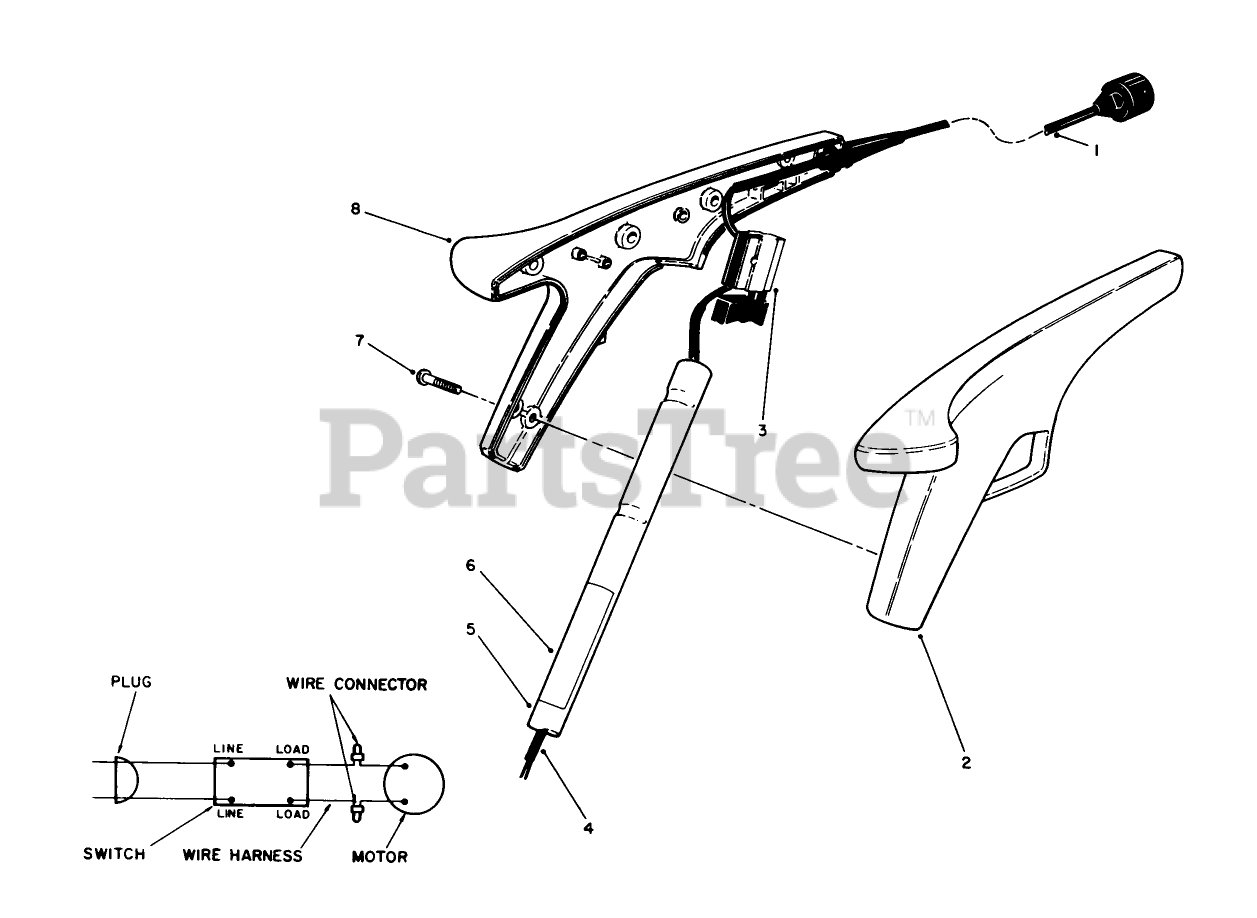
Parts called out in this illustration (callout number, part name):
1	Cord-Power
2	HAND GRIP, 8" - L.H.
3	SWITCH SINGLE SPEED
4	WIRE HARNESS
5	TUBE EXTENSION
7	#8 X .625" PHILPS PAN H
8	HAND GRIP, 8" - R.H.
